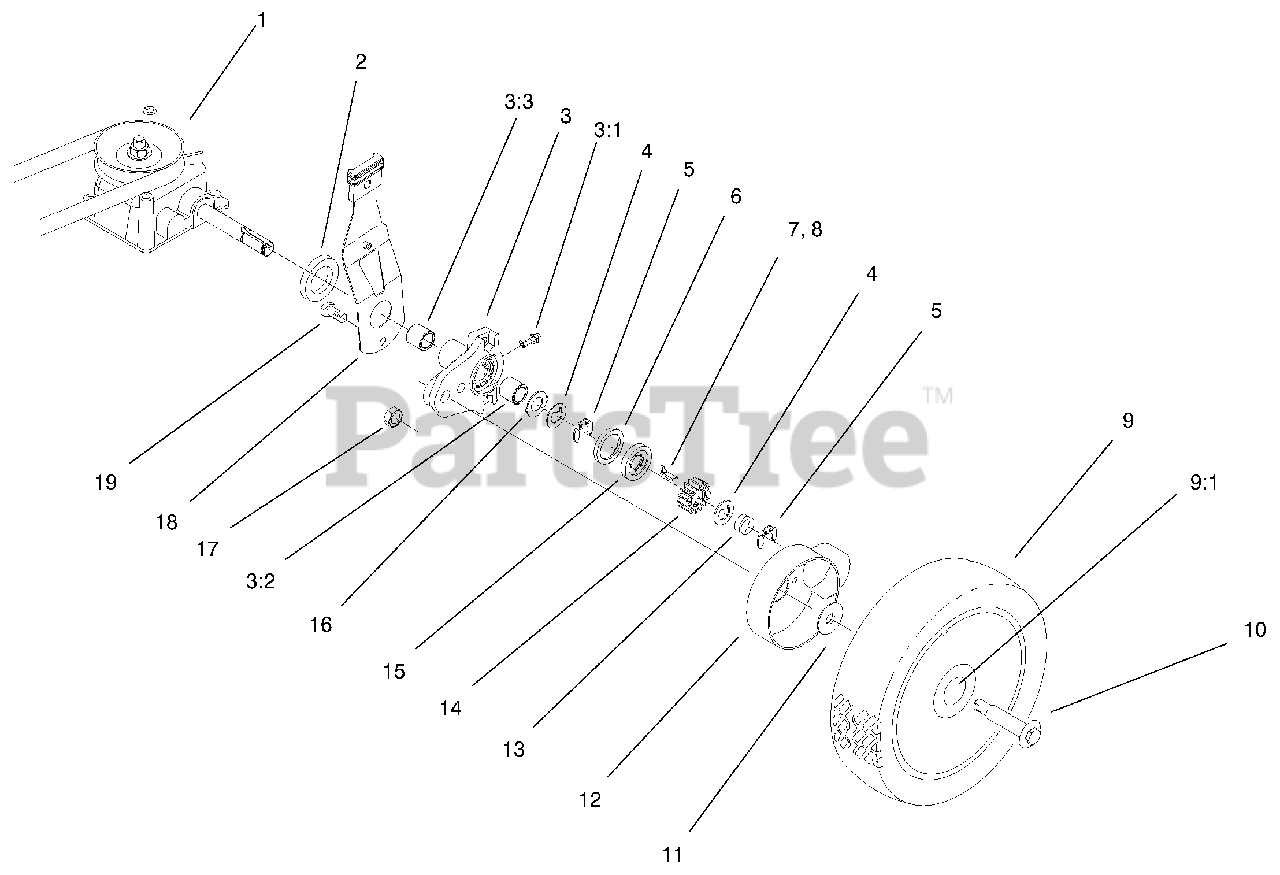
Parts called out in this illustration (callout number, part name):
2	Spacer-Axle Shaft
3	Arm ASM-Rear Height Adjustment
3:1	Fitting-Zerk
4	Washer-Thrust, Keyed
5	Ring-Klip
6	Ring-Friction
7	Key-Rocking, RH
8	Key-Rocking, LH
9	Wheel ASM
10	Bolt-Shoulder
11	Washer-Stepped
12	Cover-Wheel
13	Spring-Compression
14	Gear-Pinion
15	Washer-Clutch
16	Washer-Arm, Pivot
18	Rear Spring Arm ASM
